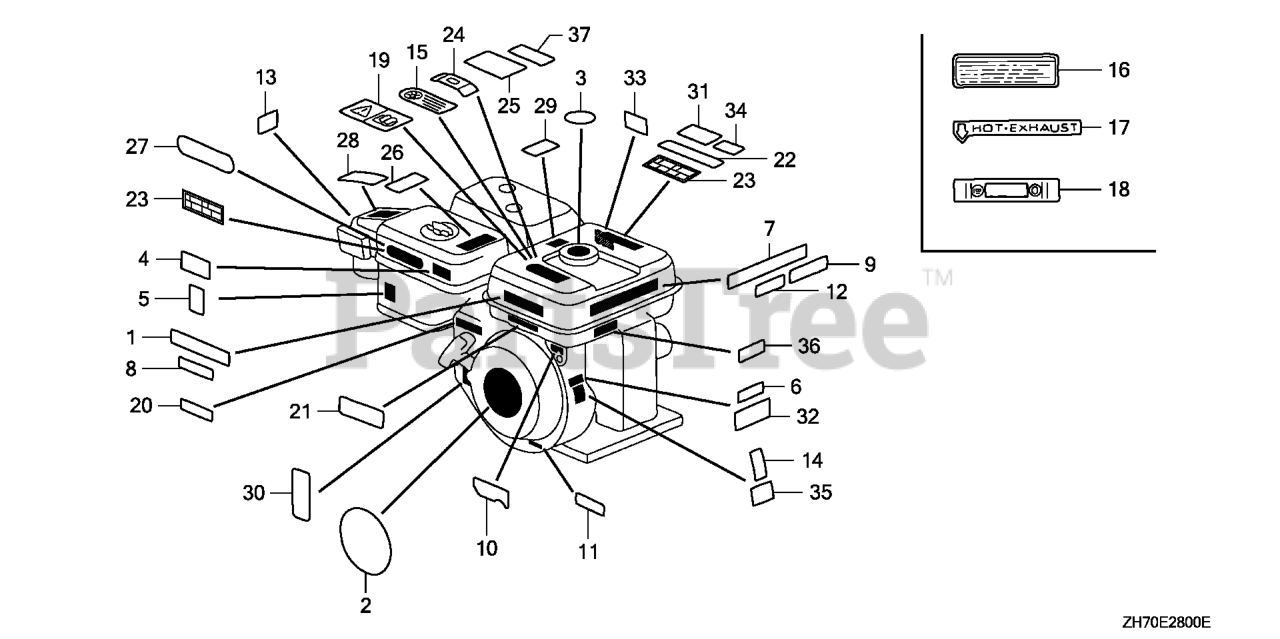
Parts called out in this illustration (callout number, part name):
1	LABEL, CAUTION (ENGLISH, ETC.)
2	EMBLEM
2	EMBLEM (GX120)
2	EMBLEM (EXTERNAL)
3	MARK, CAUTION (EXTERNAL)
5	MARK, CHOKE
6	LABEL, SPECIFICATION (EXTERNAL)
9	MARK, OIL ALERT (GERMAN) (ENGINE NO.)
9	MARK, OIL ALERT (FRENCH) (ENGINE NO.)
10	MARK, OIL ALERT (EXTERNAL)
12	MARK, OIL ALERT (ENGLISH)
14	LABEL, SPECIFICATION (EXTERNAL)
30	LABEL (E-SPEC)
